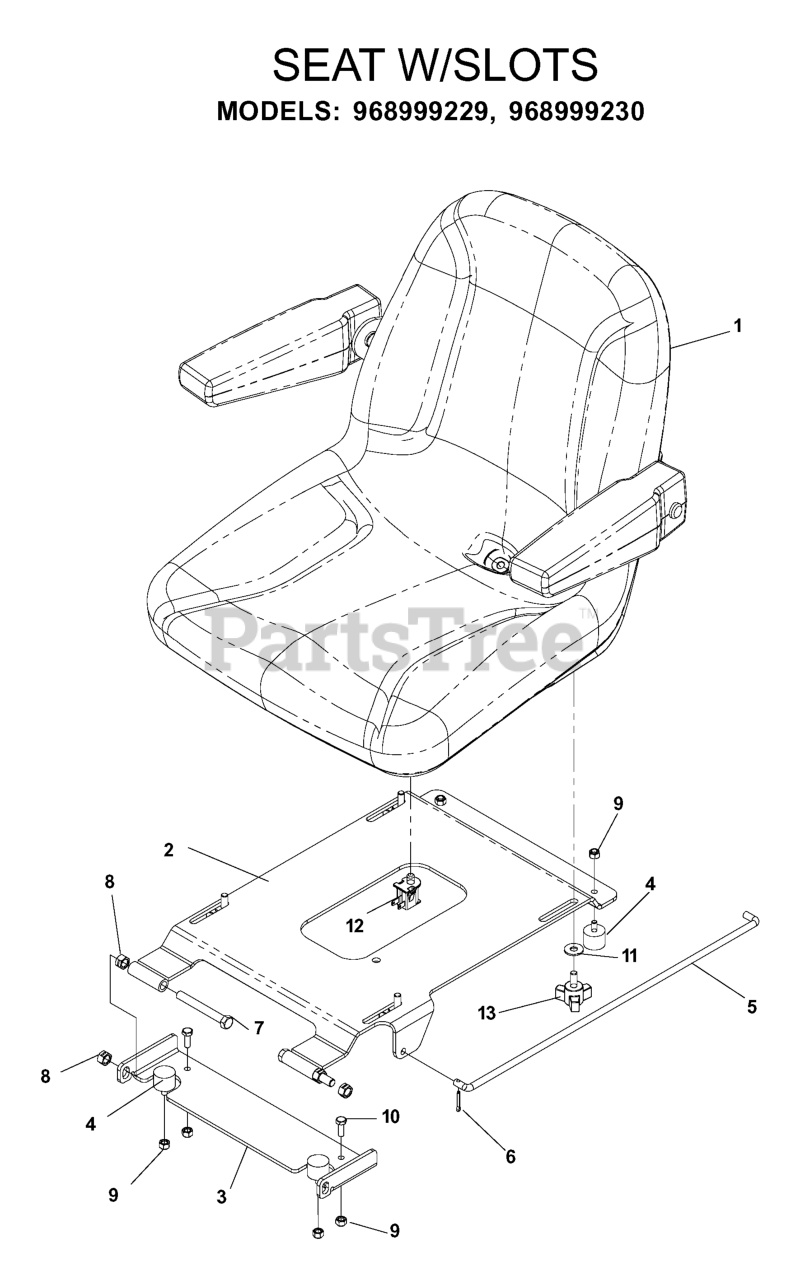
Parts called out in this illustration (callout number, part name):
1	SEAT W/ARMRESTS
2	SEAT PAN WLDMT
3	SEAT BRKT W/DECAL
4	STUD/PLATE MOUNT
6	RP_COTTER PIN 1/8 X 3/4
7	HCS 3/8C X 3
8	NUT 3/8C CENTERBLOCK
9	NUT.1/4-20.HEX.NYLOC.ZD
10	HCS 1/4C X 3/4 HCS
11	WASHER 5/16 FLAT
12	SEAT SWITCH
13	KNOB W/STUD
539104392	SEAT HARNESS
539976856	TIE, PLASTIC
